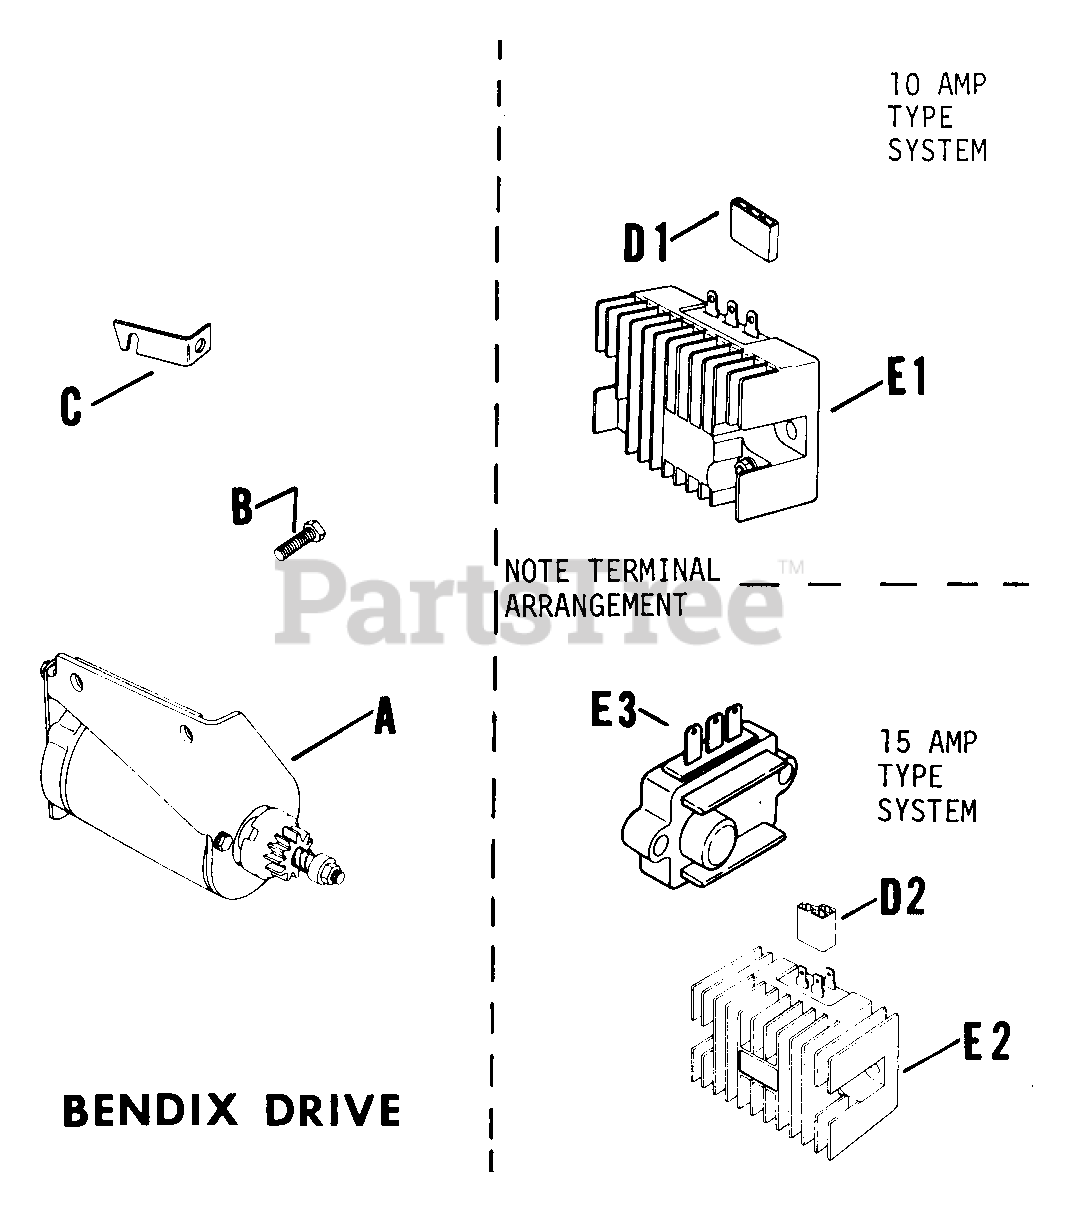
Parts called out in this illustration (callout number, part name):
A	STARTER - USE 41 098 01
A	STARTER - USE 41 098 03
B	BOLT - USE X-7-1
